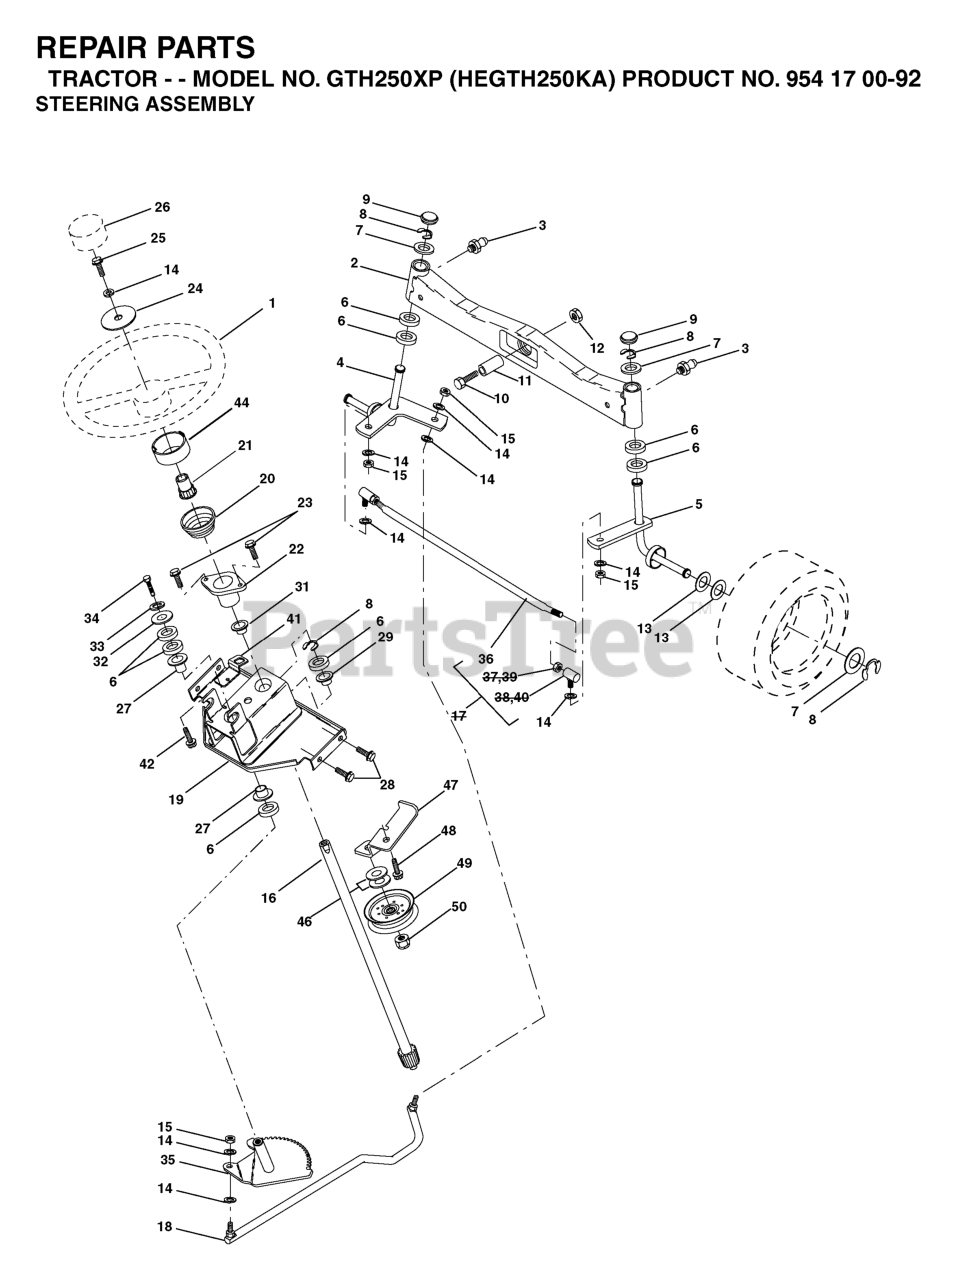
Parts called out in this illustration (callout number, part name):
1	STEERING WHEEL
2	AXLE.FRONT.CAST.MACHINE.W/ZERK
3	ZERK M
4	SPINDLE ASSY LH
5	SPINDLE ASM RH
6	THRUST WASHER
9	CAP.SPINDLE.BLACK
10	Bolt, Hex 5/8 -11 x 2 - 3/4 Gr. 5
11	TUBE, PIVOT AXLE
12	NUT-LOC,FLANGE LT
14	WASHER, LOCK 3/8
15	GRIPCO NUT
16	SHAFT ASM, STEERING
18	DRAGLINK, BALL JOINT (3SPG1401
19	SUPPORT ASM., STEERING VGT
20	BOOT, STEERING
21	STEERING WHEEL ADAPTOR
22	BUSHING, STRG. BLK
23	SCREW.TT.#10-32X.5.3/8.FLANGE
26	CAP.WHEEL.STEERING.GREY
27	BRNG T
28	SCREW, 3/8-16X3/4
29	BEARING-FLANGE GT
31	BUSHING.NYLINER.
33	WASHER.LOCK.HVY.HLCL.SPR.5/16
34	BOLT.FIN.HEX.5/16-18X3/4
35	GEAR.ASM.SECTOR.
36	ROD.TIE.NON-ADJUSTABLE
41	BRACKET INTERLOCK
42	Screw 5/16-18 x 1/2 Hex, Self Tapping 5/16-18 x 1/2
44	EXTENSION STEERING PREMIUM
45	Washer 13/32 x 1-1/20 x 11 Gauge
47	BRKT.ASM.IDLER.STATIONERY
48	SCREW 3/8-16X3/4
49	PULLEY.IDLER.FLAT.46.PR.DR.
50	NUT LOCK FLG 3/8-16 UNC
